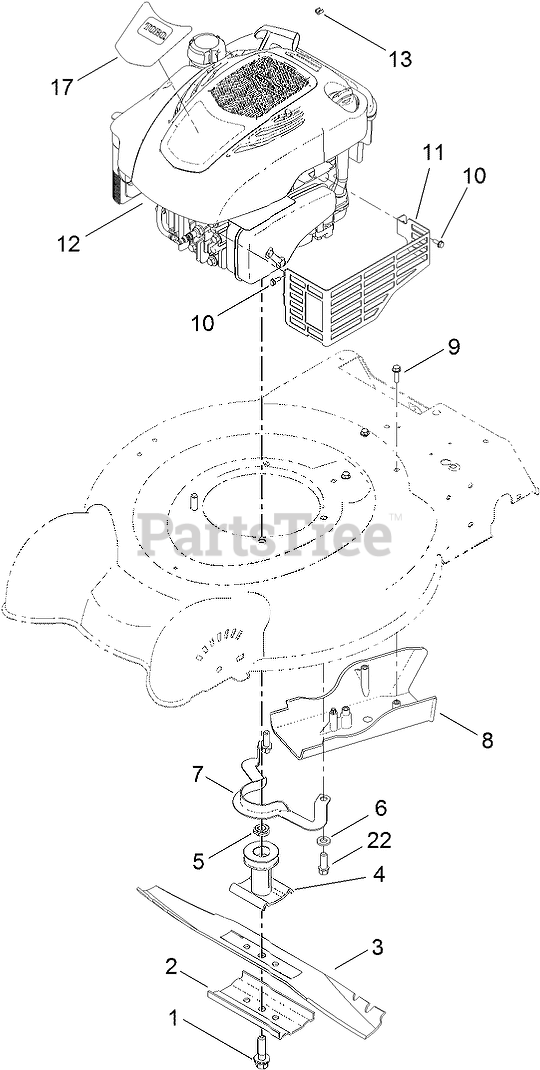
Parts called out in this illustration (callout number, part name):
1	BOLT-BLADE
2	SUPPORT-BLADE
3	BLADE-20 INCH
4	DRIVER-BLADE
5	Spacer-Driver
6	SCREW-TAPTITE
7	Guide-Belt
8	COVER-BELT
9	SCREW-HWH
10	SCREW-TAPTITE
11	SHIELD-MUFFLER
13	STOP-ROPE
17	DECAL-SHROUD
22	WASHER-FLAT
